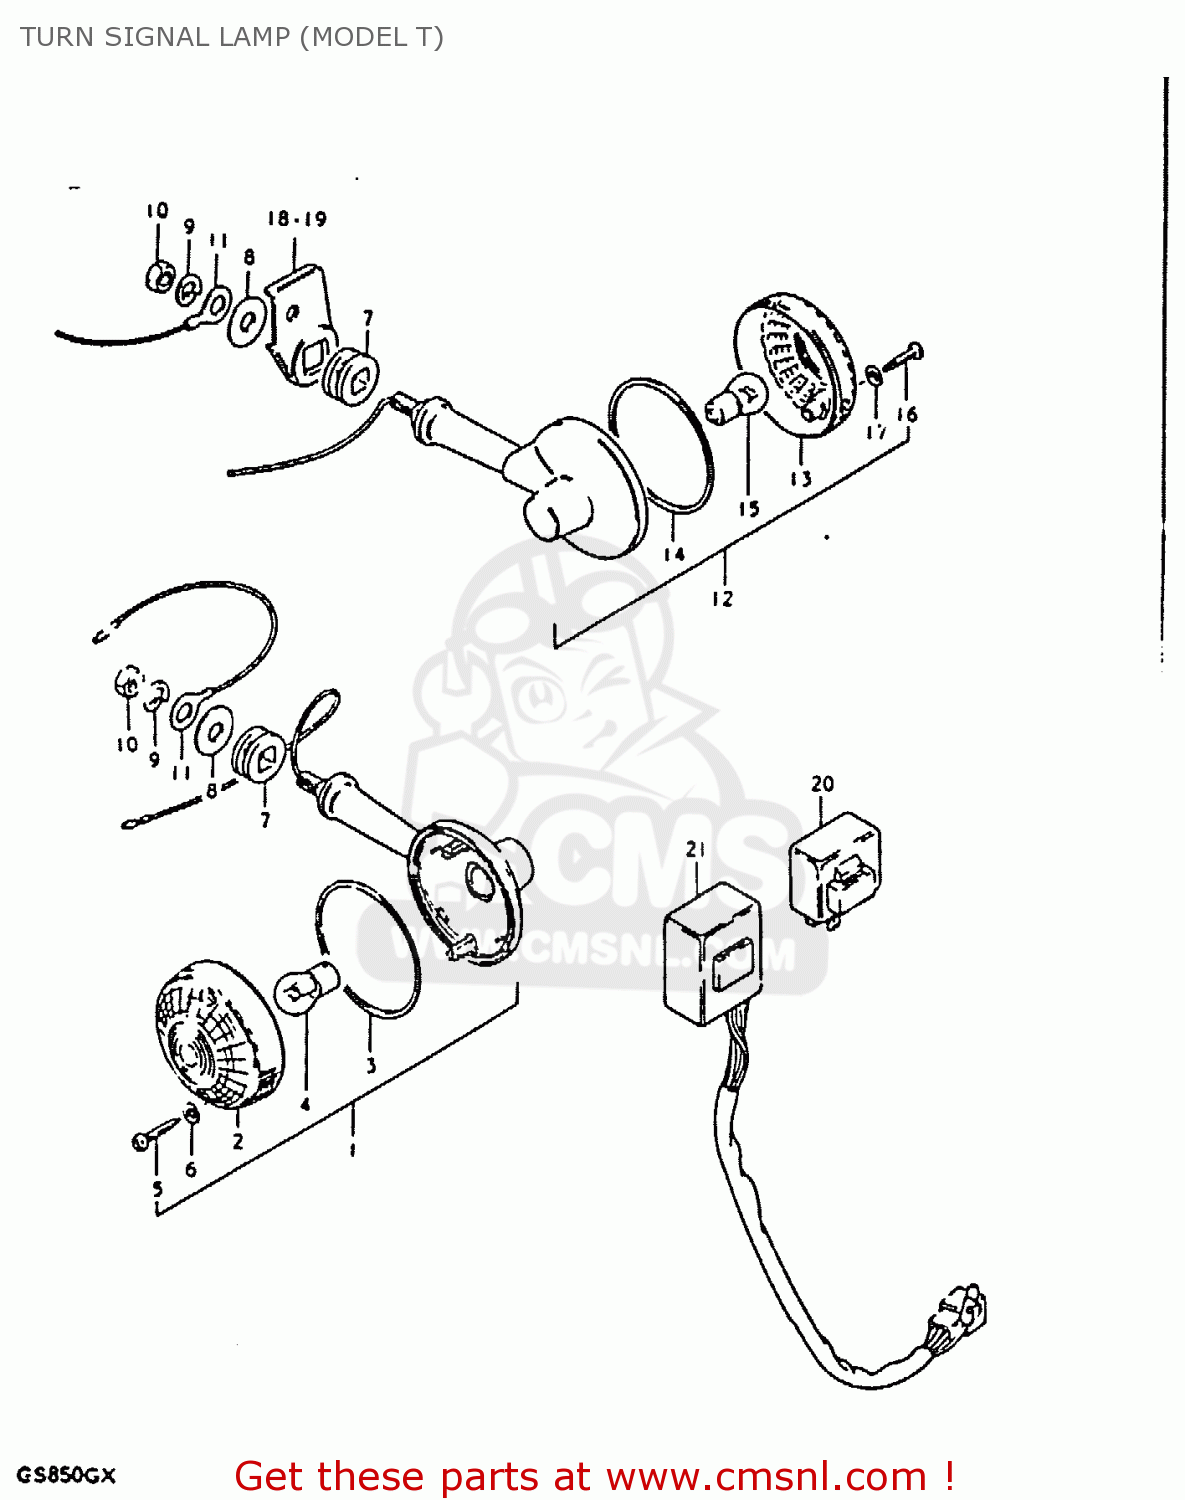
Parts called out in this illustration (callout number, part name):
1	LAMP ASSEMBLY,FRONT TURN SIGNAL
2	LENS
3	GASKET (NAS)
4	BULB(12V23W,STANLEY,A4577A)
5	BOLT
6	GASKET (NAS)
7	CUSHION
8	WASHER
9	LOCK WASHER
10	NUT
11	LEAD WIRE,EARTH
12	LAMP ASSEMBLY,FRONT TURN SIGNAL
13	LENS
14	GASKET (NAS)
15	BULB(12V23W,STANLEY,A4577A)
16	BOLT
17	GASKET (NAS)
18	BRACKET,RR TURNSIGNAL LAMP,R
19	BRACKET,RR TURNSIGNAL LAMP,L
20	RELAY,TURN SIGNAL
21	UNIT,TURN SIGNAL CONTROL
